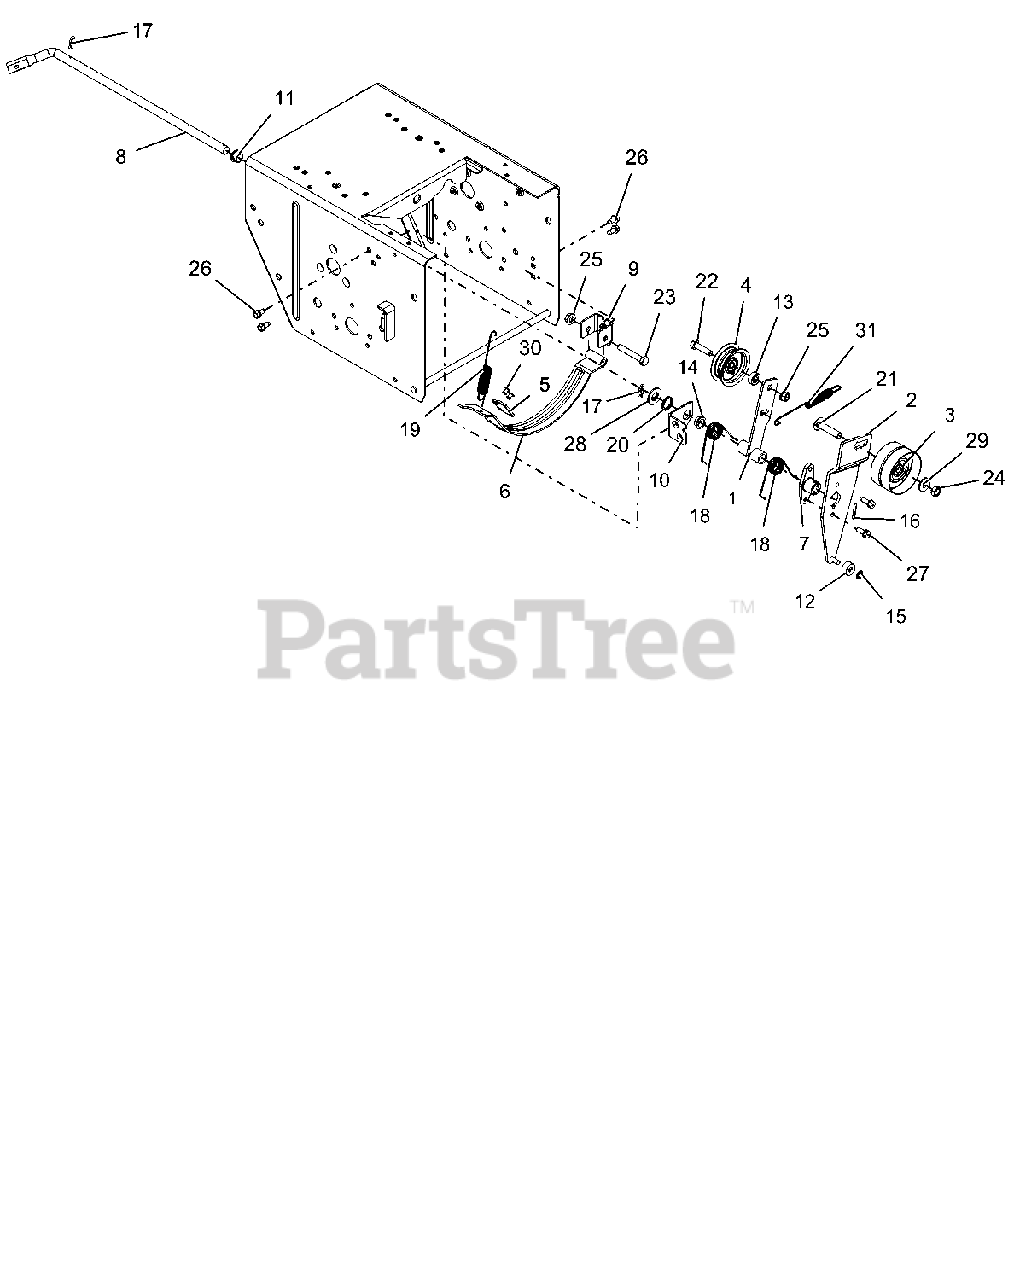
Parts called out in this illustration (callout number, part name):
1	ARM, IDLER-TRACTION
2	ARM, IDLER-ATTACHMENT
3	IDLER, FLAT-2.75 OD X .375 ID
4	IDLER, FLAT - 2.00"
5	PAD, BRAKE
6	ARM, BRAKE-ATTACHMENT
7	HUB, BRAKE ARM
8	ARM, ATTACHMENT
9	PIVOT, BRAKE
10	BRACKET, SUPPORT
11	BUSHING, POLYLINER-.50 SPLIT
12	BSHG,SLV .265 X .625 X .375
13	SPCR, BRG .315X.500X.358X.281
14	BSHG,FLANGE .500X.625X.270X.75
15	RG-RTNG-EXT .250X.010
16	PIN-ROLL .125X1.00
17	CLIP, SPRING
18	SG-TORS .067X.88
19	SG-TENS .056X.60X4.40
20	WAVE SPRING .600X.875X.25FH
21	@BLT-RHDSSQNK .38-16X1.75 G5YZ
22	@BLT-HEX .31-18X1.25 GR5 YWZC
23	@BLT-HEX .31-18X2.00 GR5 YWZC
24	@NUT-LK-CTR-JAM .375-16 YWZC
25	@NUT-LK-TOP-FLG .31-18 YWZC
26	SCR-TAP .25-20X.50 HWH TR YWZ
27	SCR-TAP-PM .25-20X.75 TR YWZ
28	@WSHR-FL-STL.531X1.06X.095YWZC
29	@WSHR-FL-STL.38X.875X.083 YWZC
30	RVT-POP .187 YZ
31	SG-TENS .06X.482X5.35
